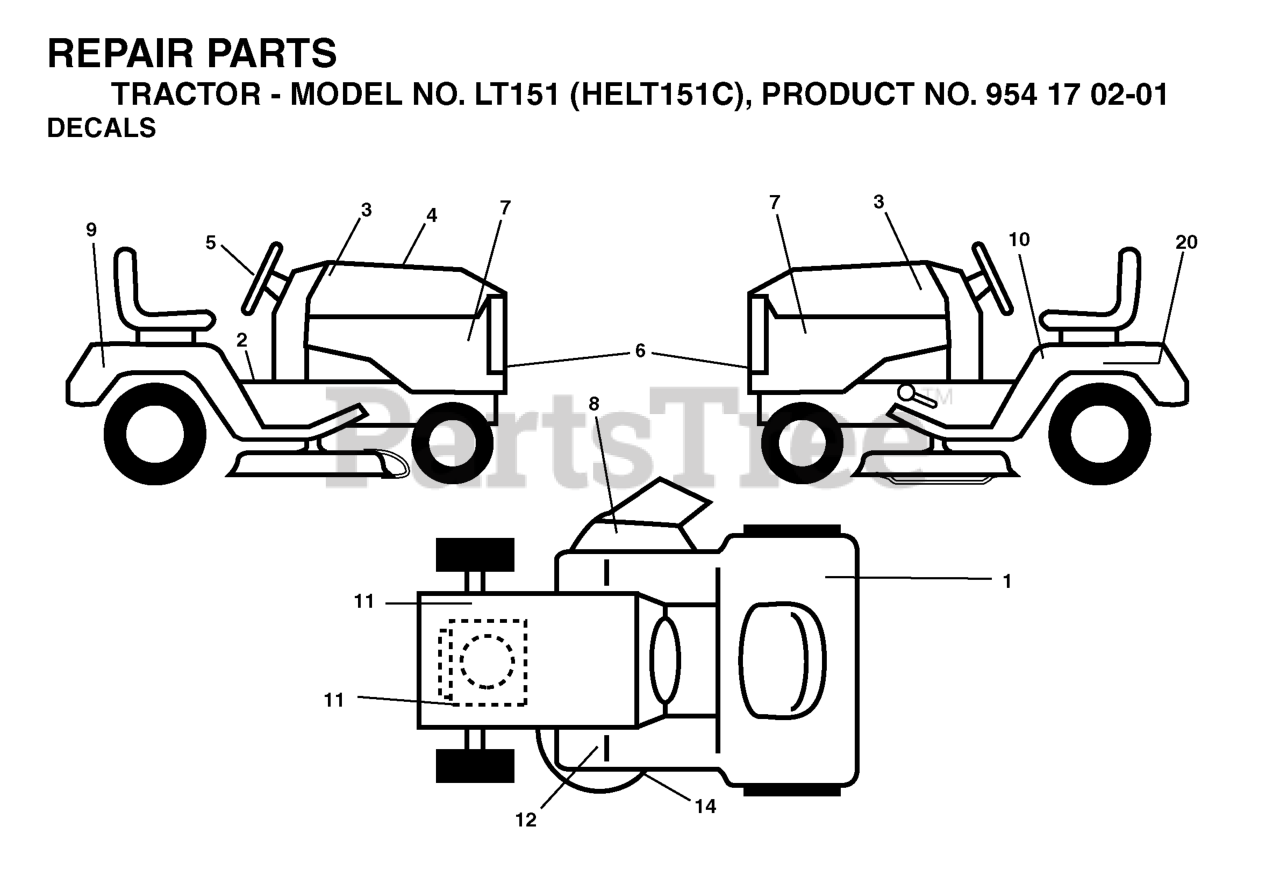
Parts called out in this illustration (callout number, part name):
1	Decal, Fender 100 DB/CE
2	DECAL PARK BRAKE
5	DECAL.STEERING.HUSQ.BLUE
7	DECAL.HOOD.HUSQVARNA.INTERNATI
8	DECAL.INTERNATIONL.CUTFINGER
10	DECAL READ OWNER'S MAN SYMS
12	DECAL
14	DECAL V-BELT SCHEMATIC
20	DECAL BTRY SYMBOLS
